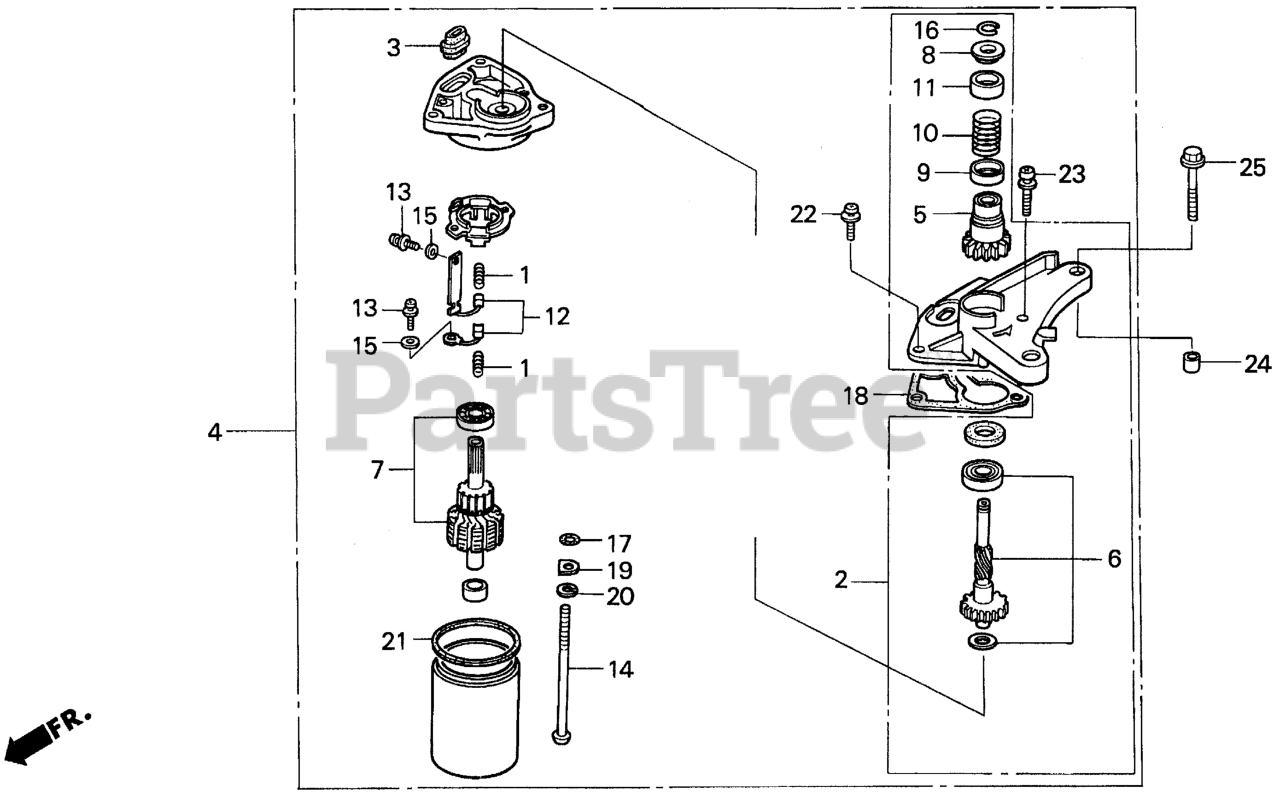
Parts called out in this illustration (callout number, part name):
1	SPRING, BRUSH
2	COVER, GEAR
4	MOTOR ASSY., STARTER
5	GEAR, PINION (16T)
6	SHAFT SET, GEAR
7	ROTOR ASSY.
8	PIECE A, STOPPER
9	PIECE B, STOPPER
10	SPRING, RETURN
11	COVER, SPRING
13	SCREW-WASHER (3X8)
14	BOLT, SETTING
15	WASHER, SPECIAL
16	CIRCLIP (7.1MM)
18	GASKET
19	WASHER, SPECIAL
20	WASHER, SPRING
22	SCREW-WASHER (5X16) Use up to Engine SN 2056819.
23	SCREW-WASHER (5X3)
24	PIN A, DOWEL (8X14)
25	BOLT, FLANGE (6X32)
